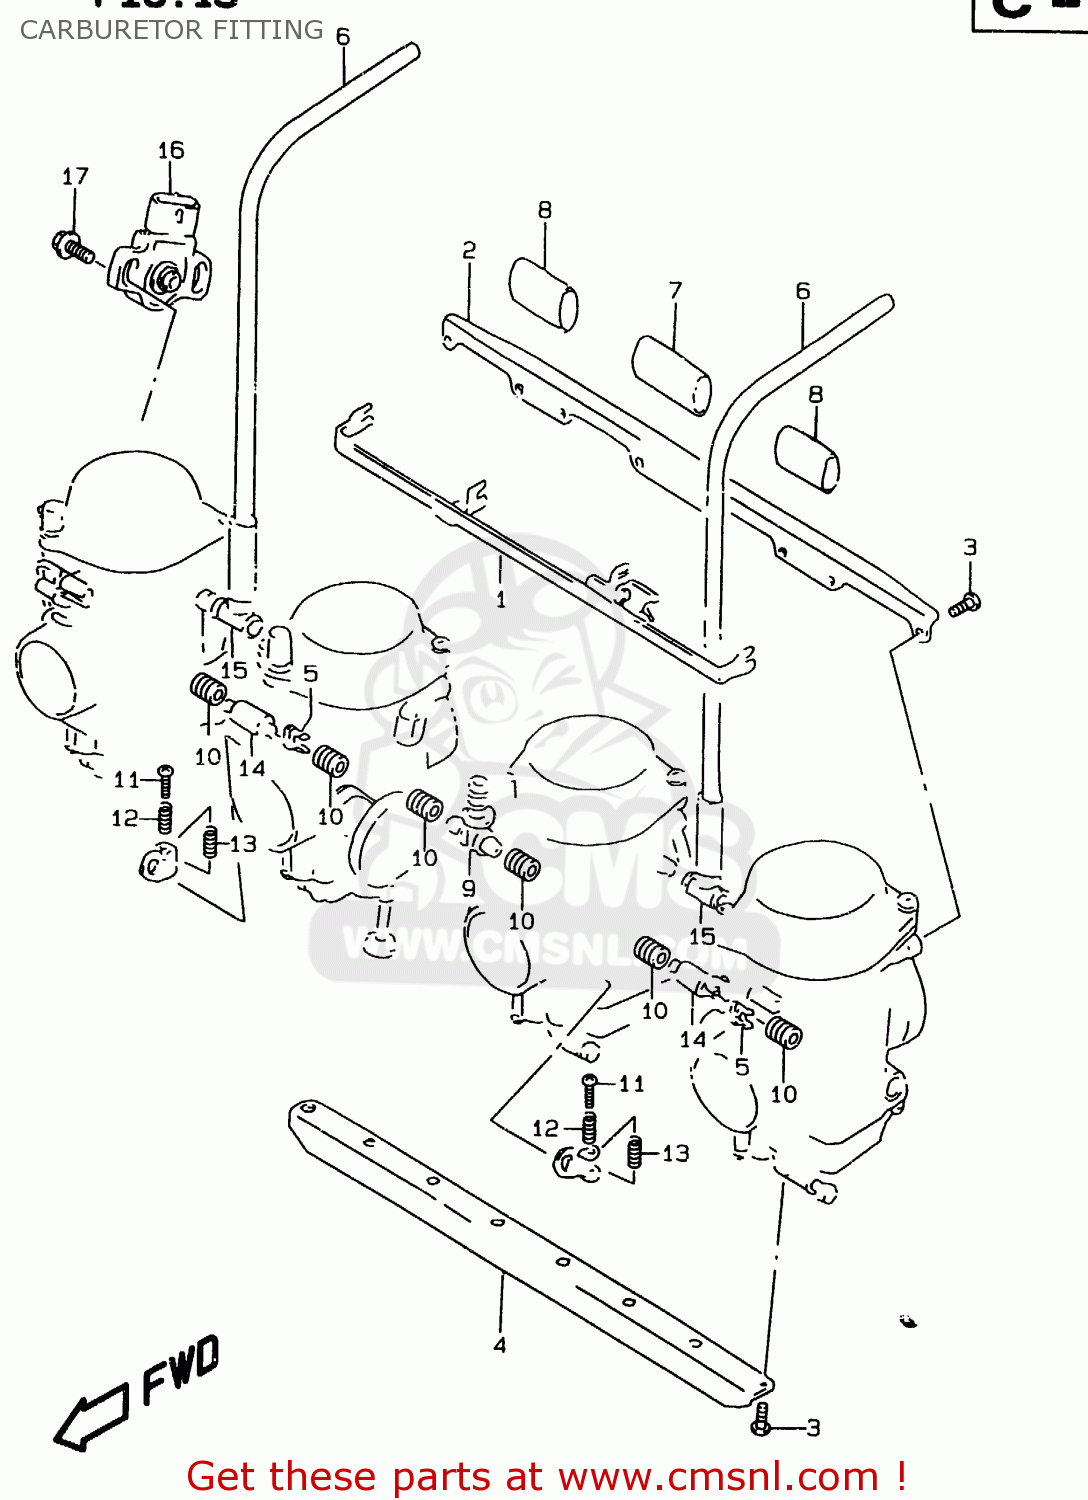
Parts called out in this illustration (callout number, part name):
1	LEVER
2	PLATE
3	SCREW
4	PLATE
5	HOLDER
6	HOSE(7X10.2X475)
7	HOSE(16X19X100)
8	HOSE(16X19X100)
9	NIPPLE
10	SEAL
11	SCREW
12	SPRING
13	SPRING
14	PIPE
15	HOSE
16	SENSOR ASSY,THROTTLE
17	SCREW,SENSOR
